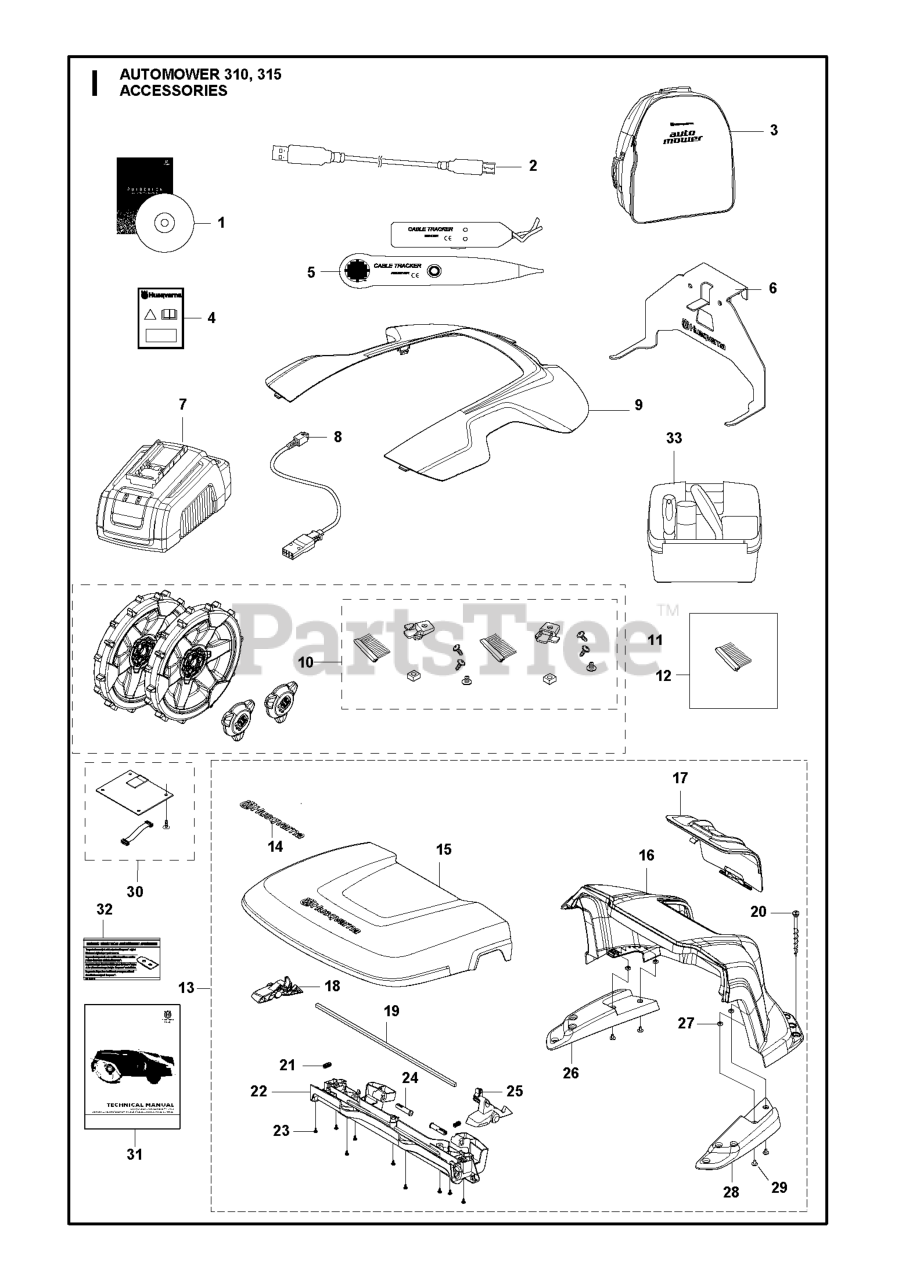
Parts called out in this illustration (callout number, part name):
1	DVD AUTOCHECK EXP SERVICE
2	CABLE WHITE ALT GREY
3	BAG
4	LABEL WARRANTY SEAL DEALER
5	TEST EQUIPMENT
6	315 WALL HANGER
7	CHARGER BATTERY TEST
8	CABLE ASSY QUICK CHARGER
9	GREY COVER
9	WHITE COVER
9	ORANGE COVER
10	WHEEL BRUSH KIT 315
11	WHEEL KIT AM310/315. HEAVY REA
12	BRUSH WITH CARTON
13	HOUSE KIT FOR 315
14	DECAL.HUSQVARNA.210MM
15	COVER LID 315
16	COVER BASE P15
17	HATCH
18	HANDLE RELEASE LEFT
19	ROD
20	SCREW KIT CS
21	SPRING SPRING CAP
22	BEAM
23	SCREW 14MM
24	HINGE PIN
25	HANDLE RELEASE RIGHT
26	SUPPORT BASE LEFT
27	NUT
28	SUPPORT BASE RIGHT
29	SCREW IHPANM M6X25 4.6 ZP-BC
30	CONNECT MODULE 2G / 3G
32	DECAL WARNING ORIGINAL BLADE E
32	ORIGINAL PARTS STICKER
33	CLEANING AND MAITENANCE KIT AM
